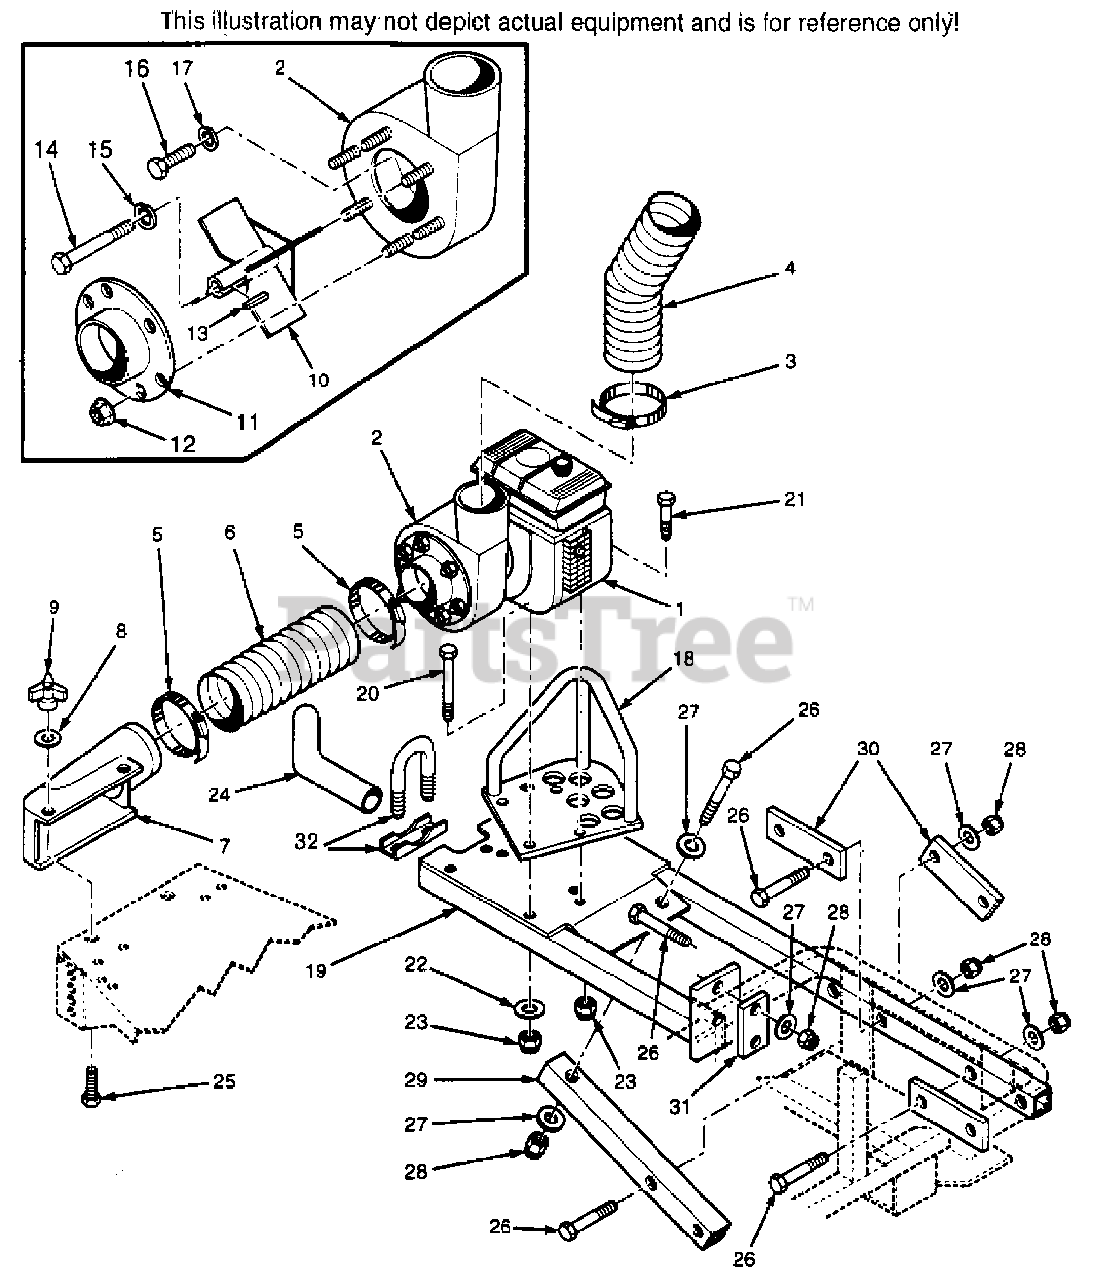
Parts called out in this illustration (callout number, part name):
1	ENGINE, BRIGGS & STRATTON 5 HP
2	BLOWER HOUSING WELDMENT
3	CLAMP, HOSE 6"
4	HOSE, 6" X 24"
5	CLAMP, HOSE 8"
6	HOSE, 8" X 29"
7	BOOT
9	ELASTIC WING NUT 3/8-16
10	FAN WELDMENT
11	BLOWER INLET ADAPTER
12	NUT, SERR. FLANGE 5/16-18
13	KEY, .25 X .25 X 1.50
14	BOLT, HEX HEAD 3/8-24 X 2.00
15	LOCKWASHER, 3/8
16	BOLT, HEX HEAD 5/16-24 X 1.0
17	LOCKWASHER, 5/16
18	ENGINE GUARD WELDMENT
19	ENGINE MOUNTING FRAME
20	BOLT, HEX HEAD 5/16-18 X 3.25
21	BOLT, HEX HEAD 5/16-18 X 1.75
22	FLAT WASHER, 5/16(.375 X .875 X .083)
23	NUT, ELASTIC STOP 5/16-18
24	TUBE, EXHAUST
25	BOLT, HEX HEAD 3/8-16 X 1.00
26	BOLT, HEX HEAD 3/8-16 X 2.50
27	FLAT WASHER, 3/8(.391 X .875 X .088)
28	NUT, ELASTIC STOP 3/8-16
29	TUBE, LOWER BRACE
30	CLAMP, REAR TUBE
31	CLAMP, FRONT TUBE
32	CLAMP, MUFFLER
